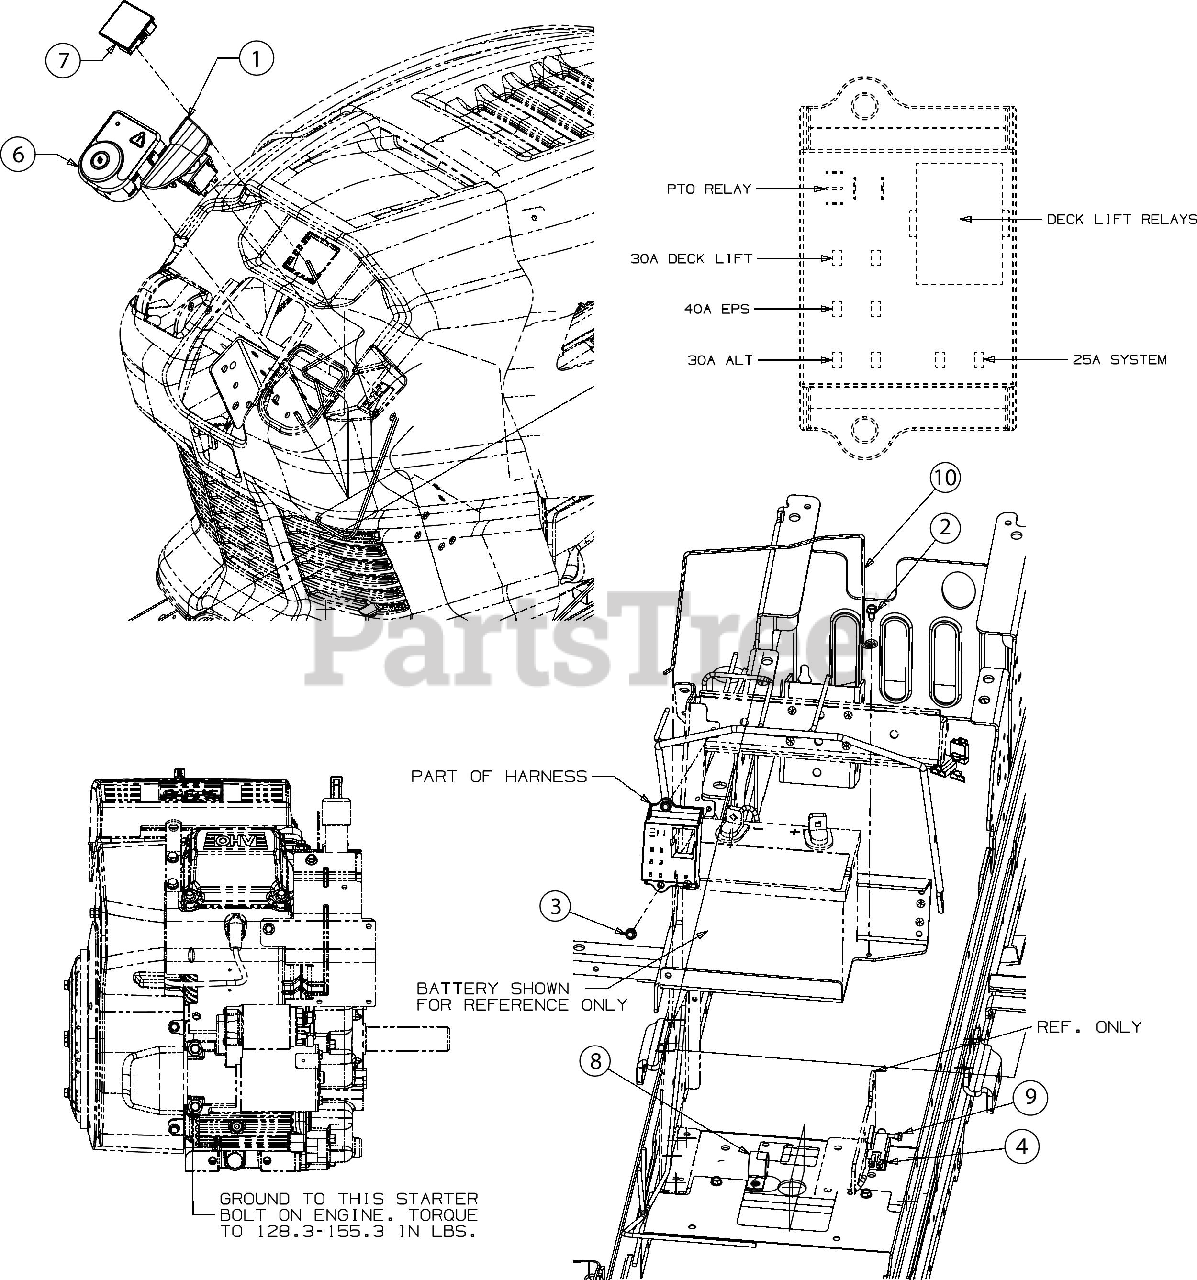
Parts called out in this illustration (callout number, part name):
1	PTO SWITCH ASSEMBLY
2	SCREW 1/4-20 X.500
3	SCREW 1/4-20 x .750
4	INTERLOCK SWITCH (NO/NC)
6	KEY SWITCH MODULE 8 PIN
7	HOUR METER/SERVICE MINDER
8	HOSE CLAMP 1.0"
9	SHOULDER SCREW
10	BATTERY STRAP
11	MAIN HARNESS ASSEMBLY
